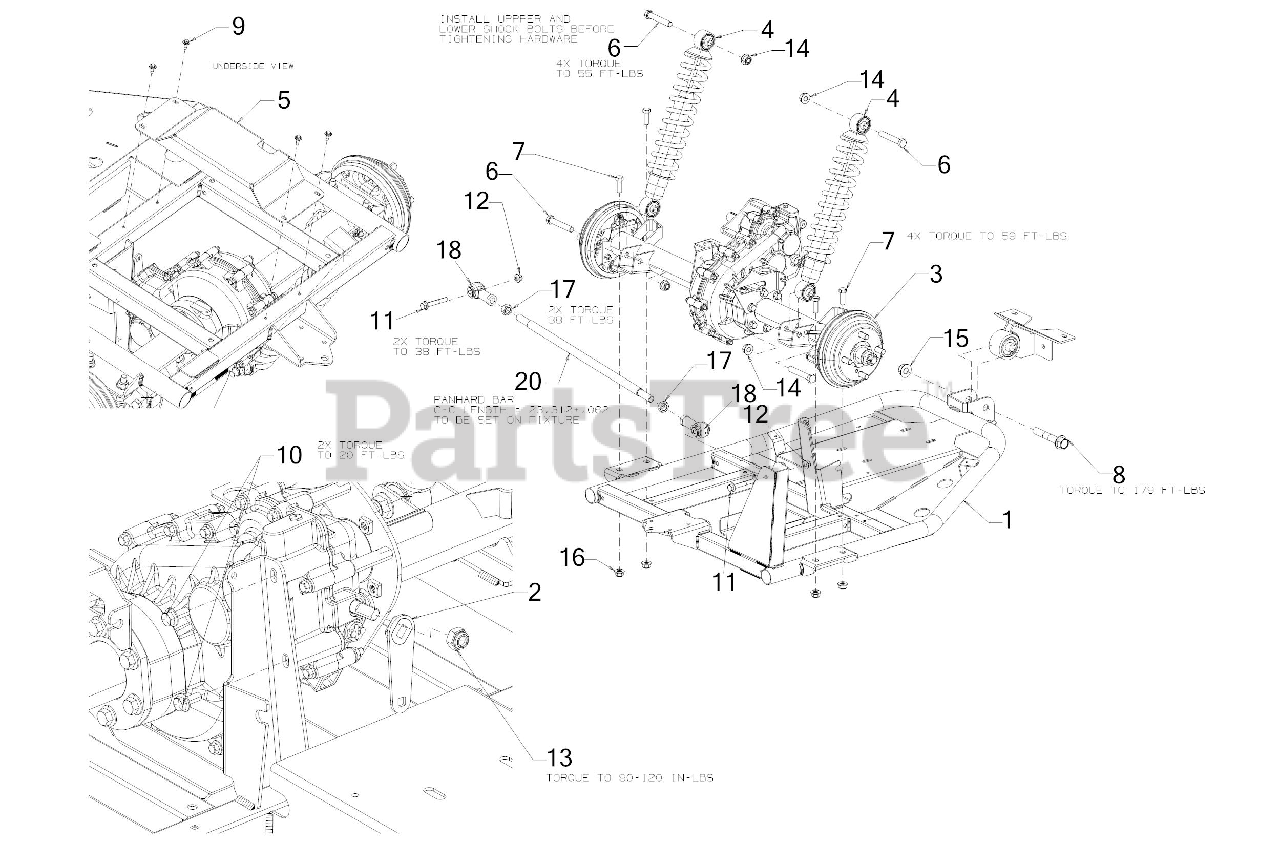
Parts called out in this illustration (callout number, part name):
1	SWING ARM FRAME ASSEMBLY
2	TRANSAXLE SHIFT CONTROL ARM
3	REAR TRANSAXLE ASSEMBLY
4	REAR SHOCK ABSORBER
5	TRANSMISSION SHIELD BRACKET
6	HEX SCREW 1/2-13 x 3.00
7	HEX SCREW 7/16-14 x 1.25
8	HEX FLANGE BOLT 5/8-11:3.75
9	SCREW M6-1 x .625
10	HEX FLANGE BOLT 5/16-24:0.75
11	HEX FLANGE BOLT 5/16-16:2.5
12	NUT 3/8-16
14	NUT 1/2-13
15	FLANGE LOCK NUT
16	HEX FLANGE LOCK NUT 7/16-14
17	HEX JAM NUT 5/8-18
18	BALL JOINT 5/8 X 5/8-18 X 1.5
20	PANHARD ROD
